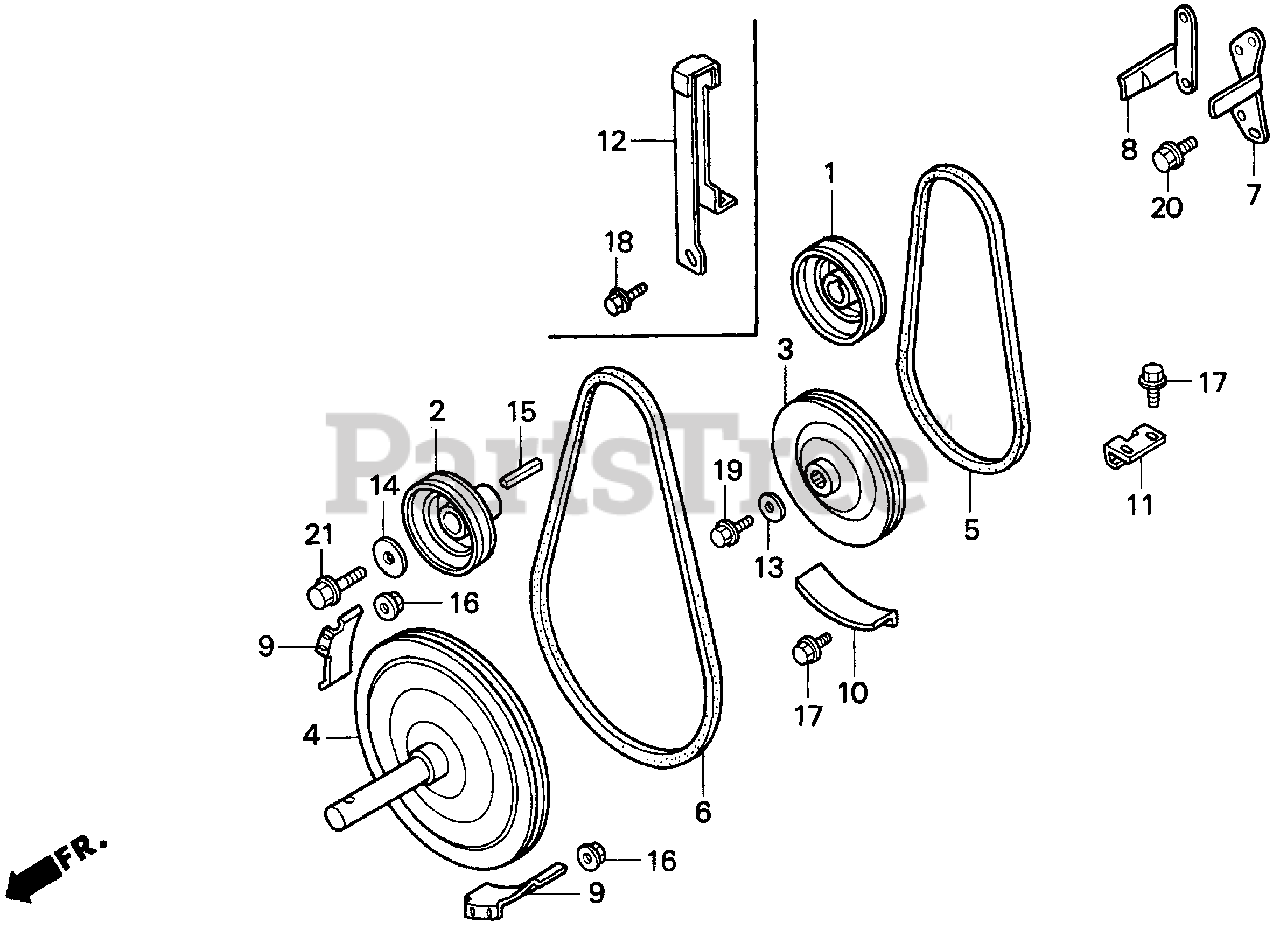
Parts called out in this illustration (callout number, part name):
1	PULLEY, WHEEL DRIVE
2	PULLEY, AUGER DRIVE
3	PULLEY, WHEEL DRIVEN (133MM)
4	PULLEY, AUGER DRIVEN (198MM)
5	V-BELT (SA-27)
6	V-BELT (SB-35)
7	STOPPER, R. BELT
8	STOPPER, L. BELT
9	STOPPER, AUGER BELT
10	PROTECTOR, BELT (WHEEL)
11	GUIDE, BELT
12	STAY, HEADLIGHT
13	WASHER, CAMSHAFT SIDE
14	WASHER, LOCK (8MM)
16	NUT, FLANGE (6MM)
17	BOLT, FLANGE (6X12)
18	BOLT, FLANGE (6X16)
19	BOLT, FLANGE (6X16)
20	BOLT, FLANGE (8X16)
21	BOLT, FLANGE (8X28)
